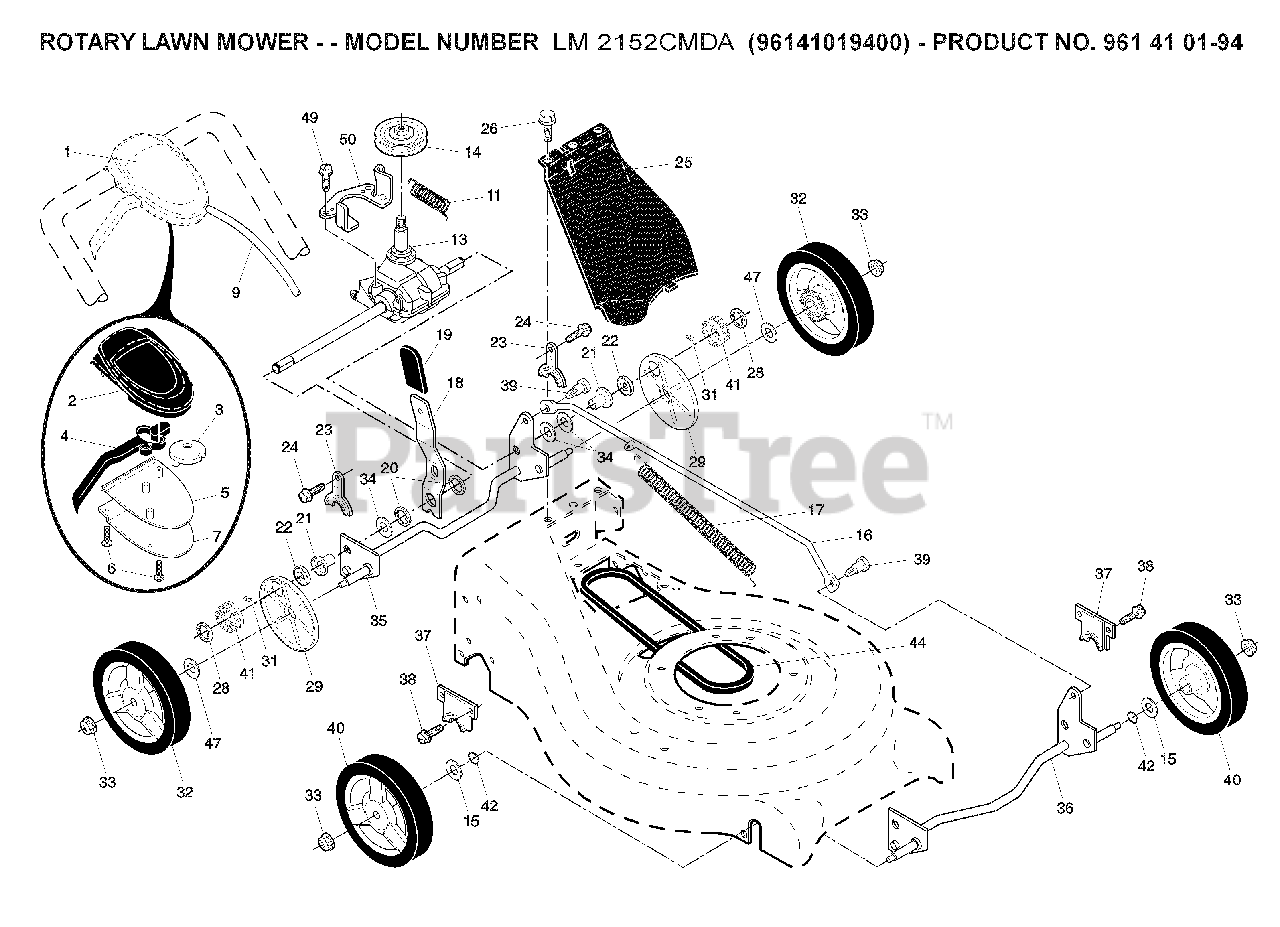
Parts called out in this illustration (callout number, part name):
2	COVER, TOP DRIVE CONTROL
3	PULLEY.CAM.DRIVE.CONTROL.EZ
5	COVER BOTTOM DRIVE CNTRL BLACK
6	SCREW, PHILLIPS HEAD 10 X 5/8
7	BRACKET.DRIVE.CONTROL.MOUNT
9	CABLE.ASSY.RGD.EZ.AUTO
13	TRANSMISSION.21.RWGD
14	PULLEY.1.PIECE
15	WASHER PM
16	ROD.CONNECTING.SPT.BLACK
17	SPRING EXTENSION
18	SPRING.SELECTOR.
19	KNOB, SELECTOR SPRING
21	BEARING SUPPORT
22	BEARING
23	BRACKET
24	SCREW 14-20 X 5/8
28	E-RING 7/16 RE
29	COVER.DUST.WHEEL
31	PAWL, DRIVE
33	NUT.HEX.FLANGE.3/8-16.LOCKNUT
35	SHAFT ASSY REAR
36	SHAFT ASSY, FRONT
37	RETAINER.FRONT.SHAFT
39	SHOULDER BOLT SEMI GIMLET PT.
41	PINIION.14.TOOTH.RGD
42	O-RING..070X.487.NEOPRENE
44	BELT.RGD.VS
47	WASHER FLUT
50	BELT KEEPER
